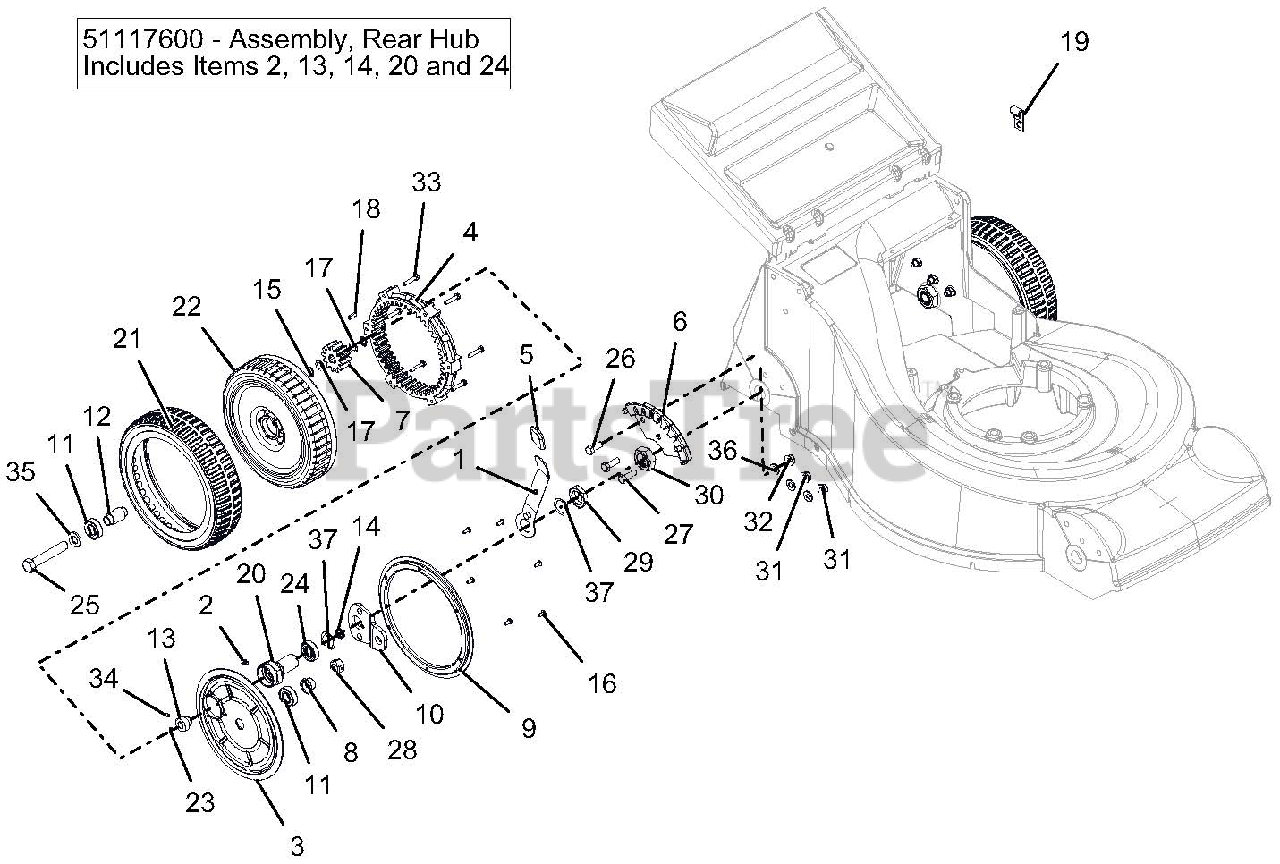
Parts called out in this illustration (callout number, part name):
1	LEVER, HEIGHT ADJUST DUAL PIN
2	FTG, 1/4-28 STRGT GREASE ZERK
3	COVER, WHEEL
4	GEAR, WHEEL
5	GRIP, HEIGHT ADJUST
6	LOCATOR, HEIGHT CONTROL
7	GEAR, PINION 12T
8	SPCR, WHEEL COVER
9	RING, TIRE RETAINING
10	BRKT, WHEEL PIN
11	BRG, WHEEL
12	BSHG, WHEEL
13	BSHG, SHLDR
14	SEAL, OIL
15	RG-RTNG-EXT 12M DIN471
16	SCR, MACHINE-#8-32 X .375 PANHD
17	WSHR, TANG
18	KEY, RECT .549X.118X.196
19	J-CLIP .25 - .406 HOLE DIA
20	HUB, REAR AXLE
21	TIRE, MOWER
22	WHEEL, ALUMINUM
23	SPRG, GEAR
24	BRG-BALL .590x1.259x.354(6000)
25	BLT-HEX .50-13X3.00 GR5 YWZC
26	BLT-HEX .31-18X.875 GR5 YWZC
27	BLT-HEX .31-18X1.00 GR5 YWZC
28	NUT-LK-CTR .50-13 YWZC
29	NUT-JAM .875-14 THIN
30	NUT-JAM .875-14
31	NUT, LK-TOP-FLG .312-18 YWZC
32	@NUT-SPNLK-FLG .312-18 YWZC
33	@SCR-MCH 10-24X1.00 HWH YWZC
34	SCR-SET, #10-24 X .25
35	WSHR-FL-STL M12 13X25X2 YWZC
36	WSHR-FL-STL.344X.688X.065YWZC
37	WASHER, WAVE
38	ASSEMBLY, REAR HUB
